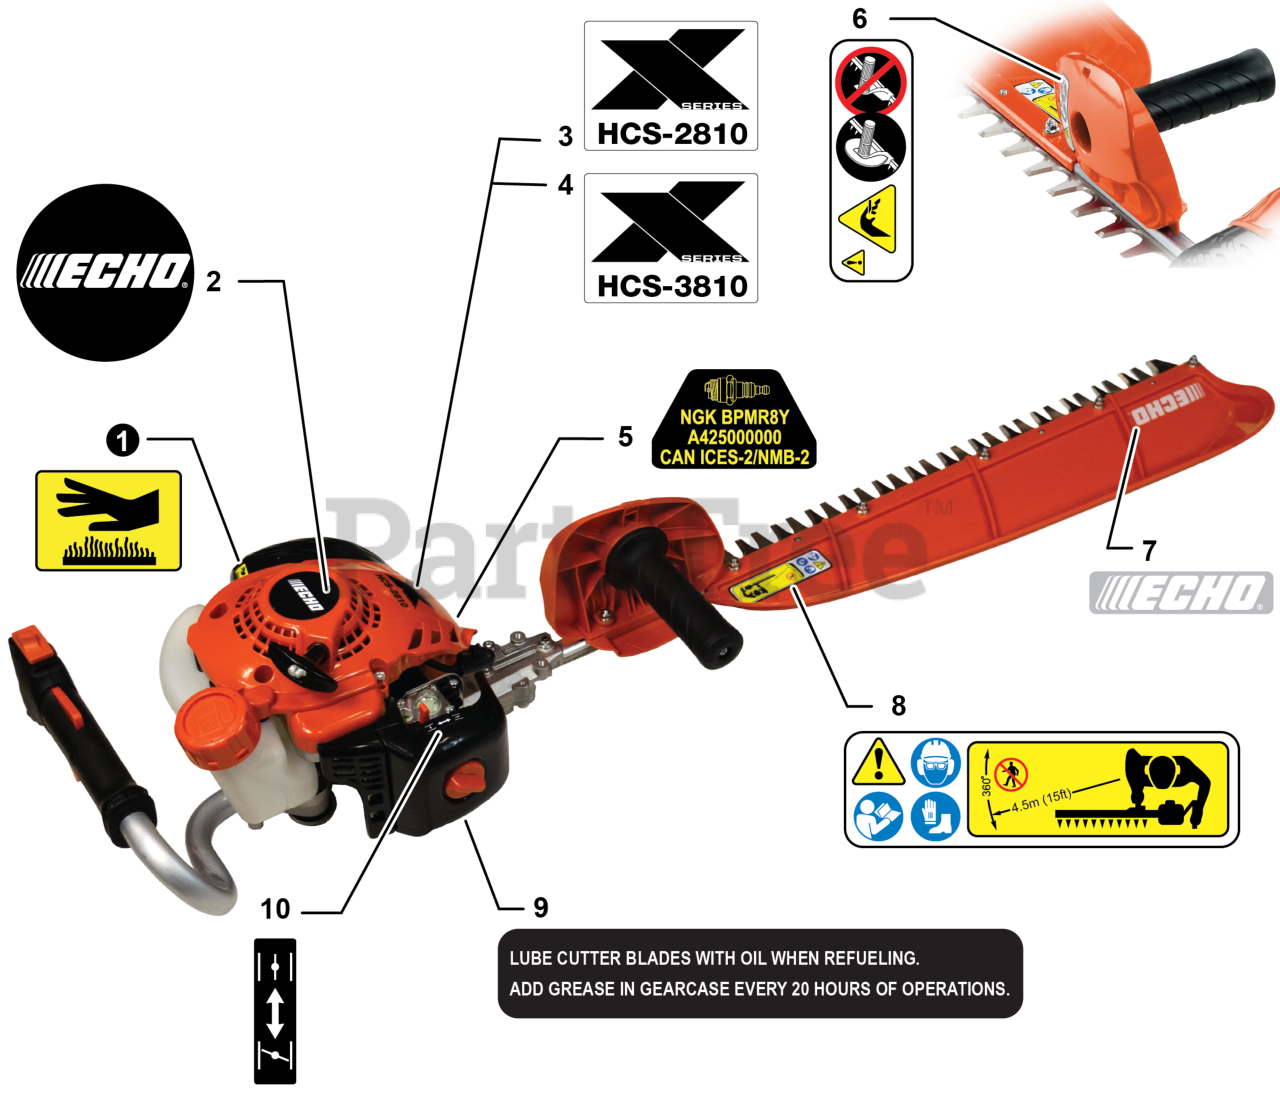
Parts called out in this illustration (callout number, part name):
1	LABEL - CAUTION - HOT
2	LABEL - STARTER - ECHO
3	LABEL - MODEL - HCS-2810
4	LABEL - MODEL - HCS-3810
5	LABEL - SPARK PLUG - BPMR8Y
6	LABEL - CAUTION - ISO
7	LABEL - ECHO
8	LABEL - CAUTION
9	LABEL - LUBE BLADES
10	LABEL - CHOKE
